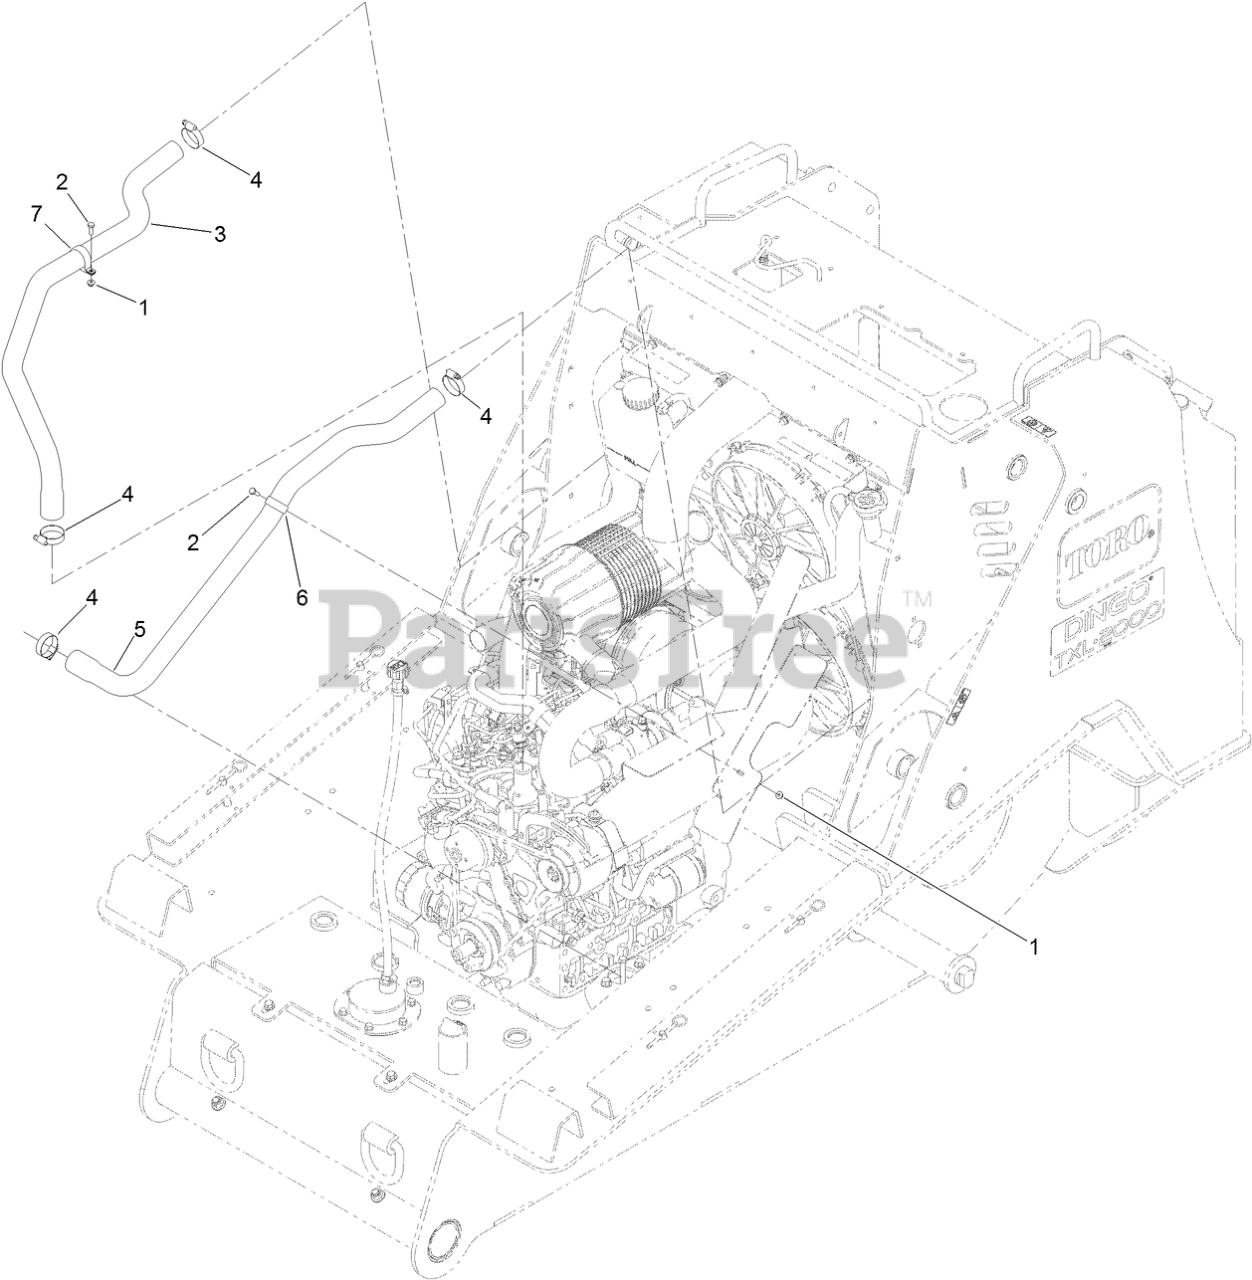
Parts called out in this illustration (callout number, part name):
1	NUT-HF
2	SCREW-HHF
3	HOSE-RADIATOR, UPPER
4	CLAMP-HOSE
5	HOSE-RADIATOR, LOWER
6	CLAMP-R
7	CLAMP-R
